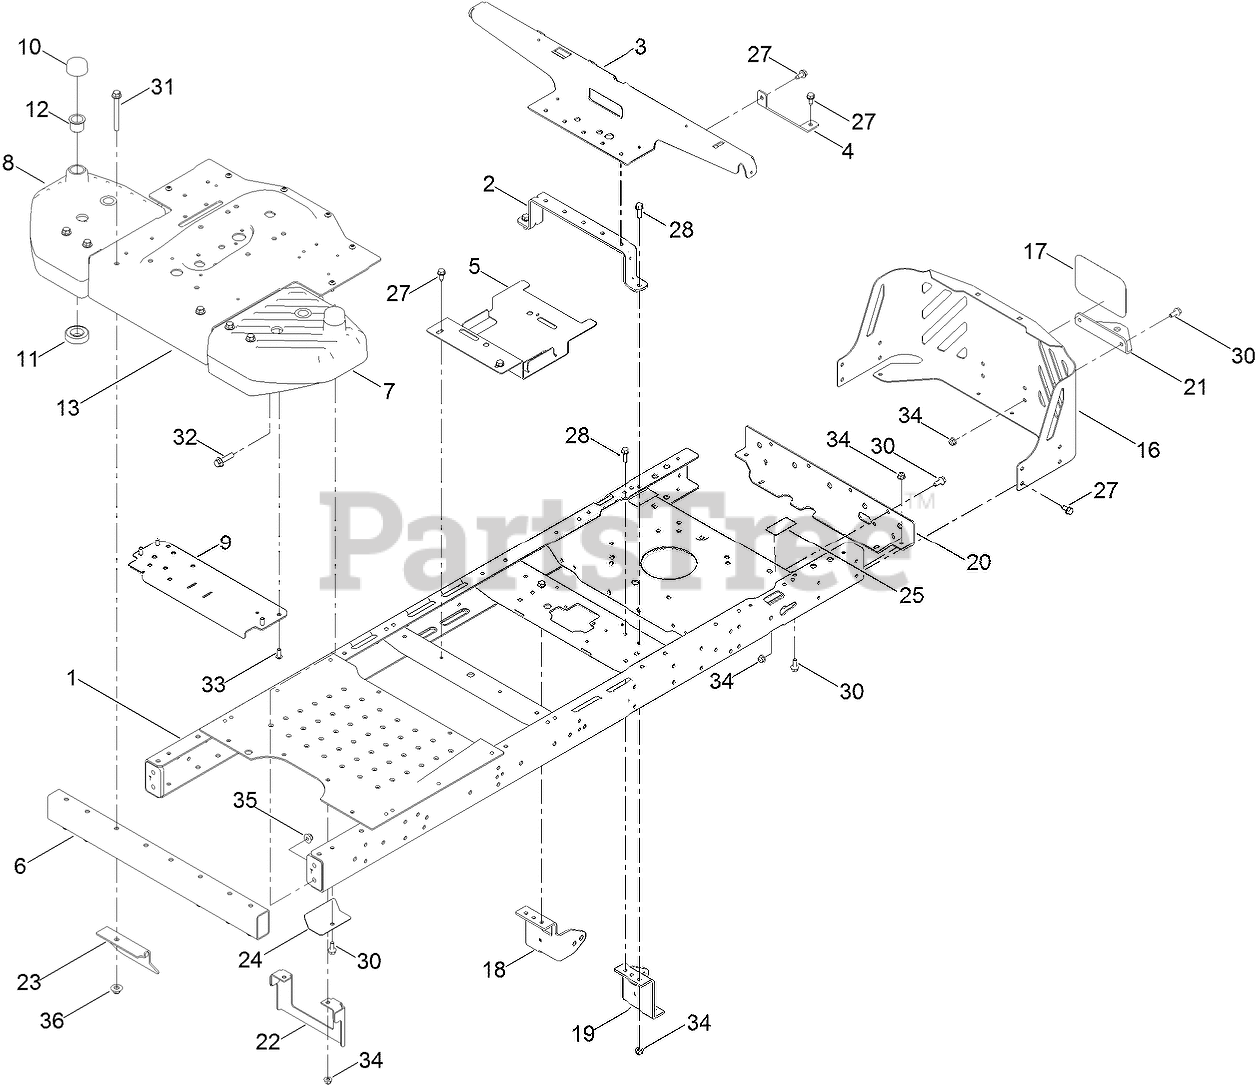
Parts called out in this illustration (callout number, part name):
1	FRAME ASM
2	BRACE-SEAT, REAR (NARROW)
3	SUPPORT-POD
4	SUPPORT-TANK, REAR
5	BRACKET-BATTERY
6	TUBE-FRONT, NARROW
7	HOUSING-SPINDLE, LH
8	HOUSING-SPINDLE, RH
9	PLATE-BRIDGE, NARROW
10	CAP-CASTER
11	BEARING-BALL
12	BUSHING-PIVOT
13	PAN-STEER, FRONT
16	GUARD-ENGINE, NARROW
17	DECAL
18	MOUNT-HYDRO, FRONT (RIGHT)
19	MOUNT-HYDRO, FRONT (LEFT)
20	CROSSMEMBER-REAR, NARROW
21	BRACKET-HITCH
22	BRACKET-UPSTOP
23	GUARD-FRONT
24	PLATE-GUARD
25	DECAL-BYPASS
27	SCREW-HWHTF
28	SCREW-HHF
30	SCREW-HHF
31	SCREW-HHF
32	SCREW-HHF
33	SCREW-HSBH
34	NUT-HF, NI
35	NUT-HF, NI
36	NUT-FLANGE, NI
